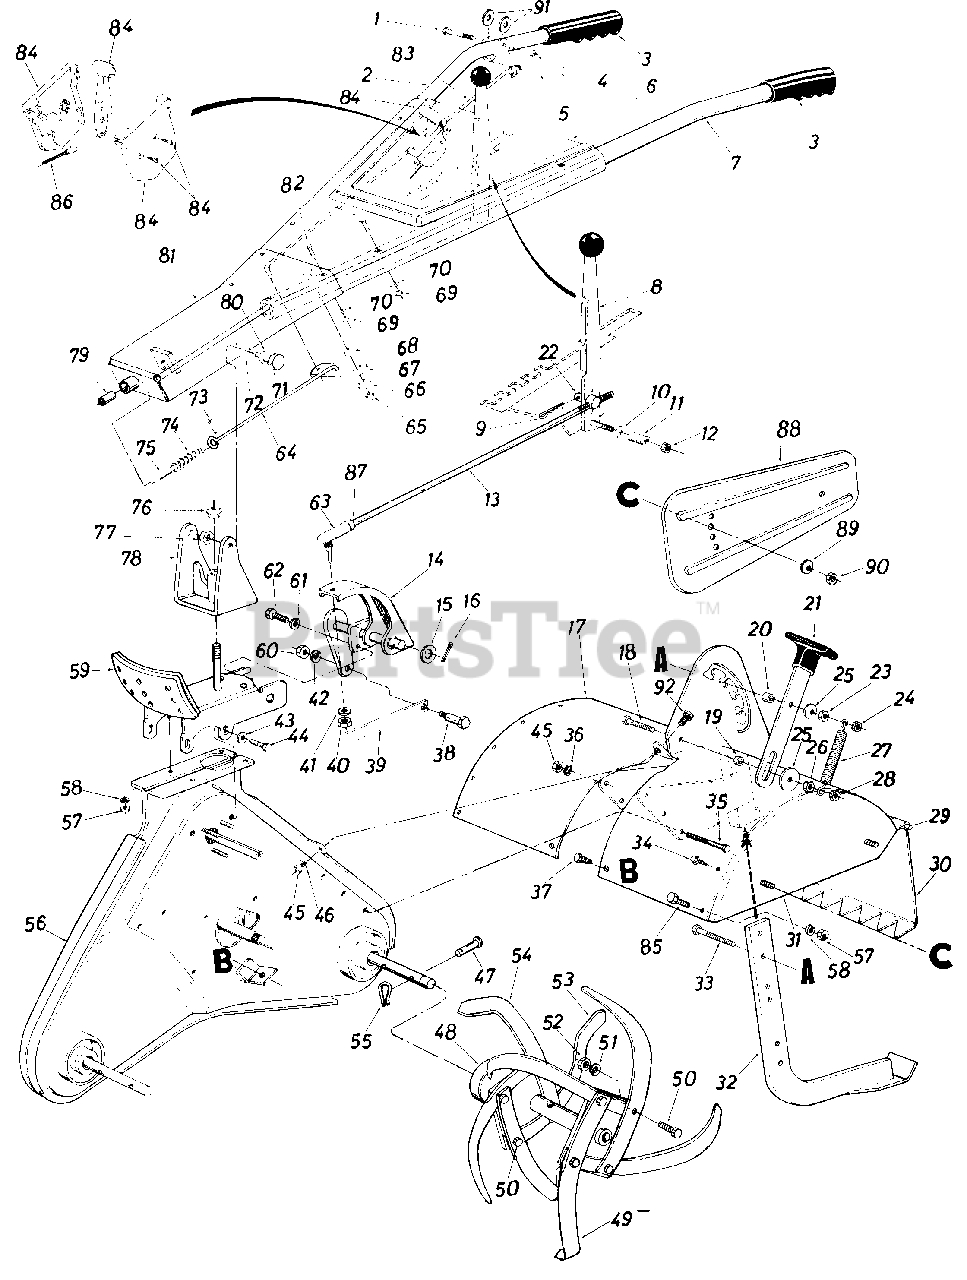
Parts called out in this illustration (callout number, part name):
1	Hex Bolt 1/4-20 x 1.75" Lg.*
2	Handle R.H.
3	Grip
4	Hex Cent. L-Nut 1/4-20 Thd.
5	Clutch Grip
6	Handle Panel Ass'y.
7	H and I e L.H.
8	Clutch Handle Ass'y.
9	Hairpin Cotter
10	Belleville Wash. .38" I.D.
11	Compression Spring .88" O.D. x .81" Lg.
12	Hex Cent L-Nut 3/8-24 Thd.
13	Gear Shift Rod
14	Pivot Horn Ass'y.
15	Fl-Wash. .630 I.D. x 1.0" O.D. x .063
16	Cotter Pin 1/8" Dia. x .75" Lg.
17	Tine Shield Ass'y.
18	Hex Bolt 3/8-16 x 1.5" Lg.
19	Spacer .38 I.D. x .50 O.D. x .18 Lg.
20	Spacer .38 I.D. x .50 O.D. x .38 Lg.
21	Depth Bar Handle Ass'y. w/Knob
22	Ferrule
23	Hex Nut 3/8-16 Thd.
24	Hex Ins. L-Nut 3/8-16 Thd.
25	Fl-Wash. .38 I.D. x 1.50 O.D. x . 13
26	Hex Nut 3/8-16 Thd.
27	Spring Depth Bar
28	Hex Ins. L-Nut 3/8-16 Thd.
29	Hinge Rod
30	Tine Shield Hinge Flap A ss'y.
31	1 Side Cover Tine Shield L.H.
32	Depth/Drag Bar Ass'y.
33	Hex Bolt 3/8-16 x 1.75" Lg.*
34	Hex Wash. Hd. Self-Tap Scr. 5/16-18 x .62" Lg.
35	Hex Bolt 3/8-24 x 3.0" Lg.
36	L-Wash. 3/8 I.D.
37	Hex Wash. Hd. Self-Tap Scr.
38	Shoulder Bolt .50" Dia. x .25" Lg.
39	Control Bracket
40	Hex Ins. L-Nut 3/8-24 Thd.
41	L-Wash. 3/8 I.D.
42	L-Wash. 3/8 I.D.
43	Belleville Wash.
44	Hex Wash. Hd. Self-Tap Scr.
45	Hex Nut 3/8-24 Thd.*
46	L-Wash. 3/8" Scr.*
47	Clevis Pin
48	Tine Adapter Ass'y.
49	L.H. Tine Ass'y. Comp.
50	Hex Bolt 3/8-24 x 1.25" Lg.*
51	L-Wash. 3/8" I.D.*
52	Hex Nut 3/8-24 Thd.*
56	Chain Case Ass'y. Cornp.
57	Hex Nut 5/16-18 Thd.*
58	L-Wash. 5/16" I.D.*
59	Handle Positioner Ass'y.
60	Hex Ins. L-Nut 3/8-16 Thd.
61	L-Wash. 5/16" I.D.*
62	Hex Wash. Hd. Self-Tap Scr.
63	Rod End 3/8-24 Thd.
64	Lower Handle Control Rod
65	Hex Nut 5/16-18 Thd.*
66	Pivot Handle Brg.
67	Pivot Handle Link
68	Bushing Wash.
69	Hex Nut 5/16-18 Thd.*
70	L-Wash. 5/16" I.D.*
71	Shld. Bolt .500" Dia. x .660
72	Belleville Wash. .505" I.D. x 1.00" O.D.
73	Cotter Pin 1/8" Dia. x .75" Lg.*
74	Compression Spring
75	Locking Pin
76	Hex Ins. L-Nut 5/8-16 Thd.
77	Hex Top L-Nut 3/8-16 Thd.
78	Pivot Brk't. Ass'y.
79	Sleeve Brg. .50" I.D. x .62" O.D. x 1.12" Lg.
80	Fl-Wash. .50" I.D. x 1.00" O.D. x .090
81	Handle Mtg. Brk't. Ass'y.
82	Carriage Bolt 5/16-18 x 1.75" Lg.*
83	Handle Lock Rod
84	Throttle Control Box Ass'y.
85	Hex Bolt 5/16-18 x .75" Lg.*
86	Throttle Control Wire
87	Hex Jam Nut 3/8-24 Thd.
90	Hex Nut 5/16-18 Thd.
91	Fl-Wash. 1/4" I.D.
92	Hex Bolt 3/8-24 x .75" Lg.
